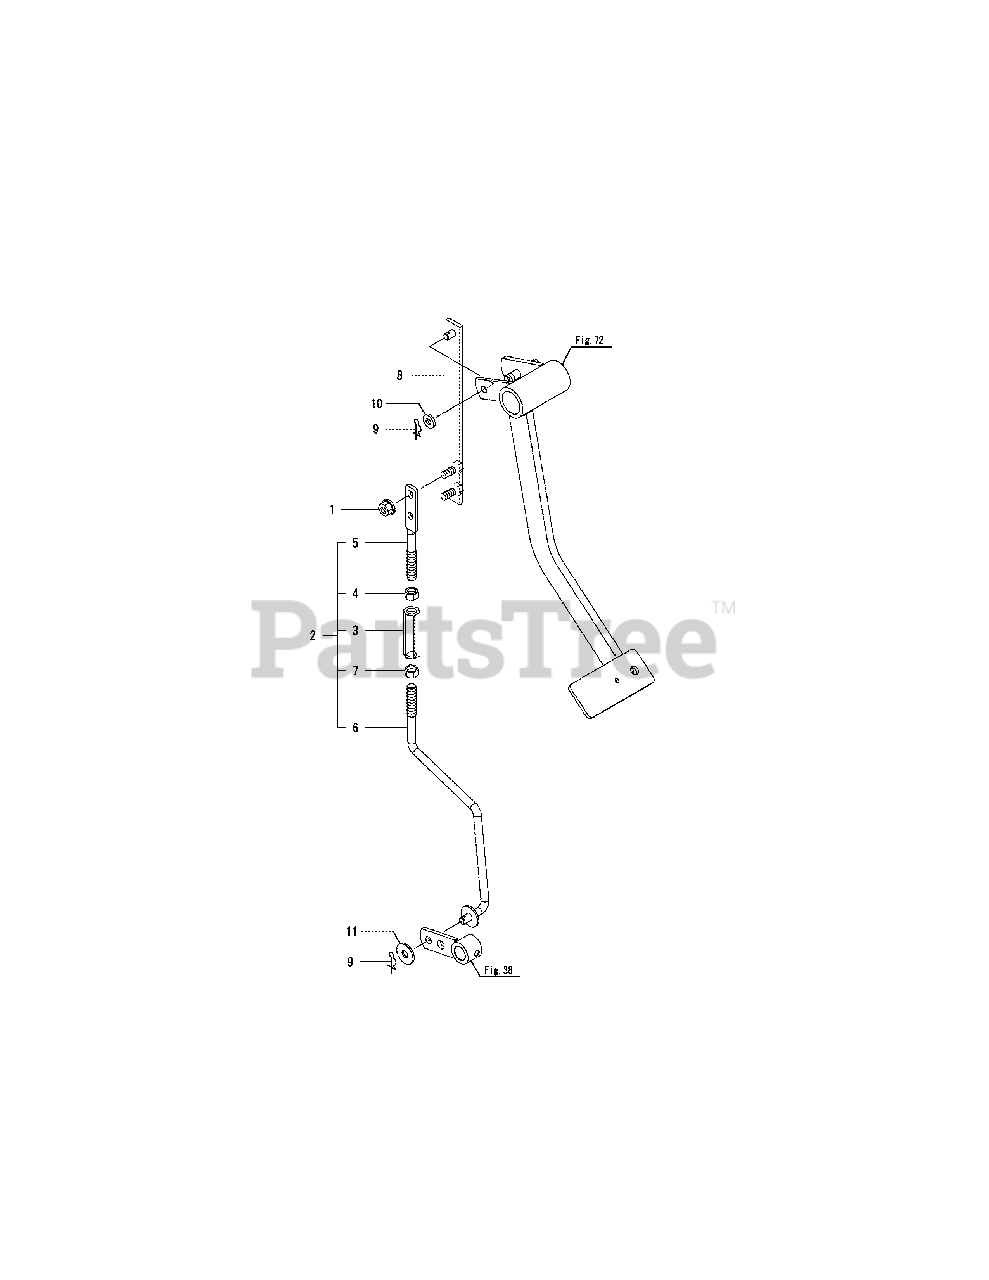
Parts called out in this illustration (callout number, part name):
1	NUT W/WASHER 8
2	TURNBUCKLE ASSY
3	TURNBUCKLE M10
5	ROD, L.H. SCREW
6	ROD ASSY, R SCREW
9	PIN 8,COME-OFF SNAP
10	WASHER 8, POLISHED
